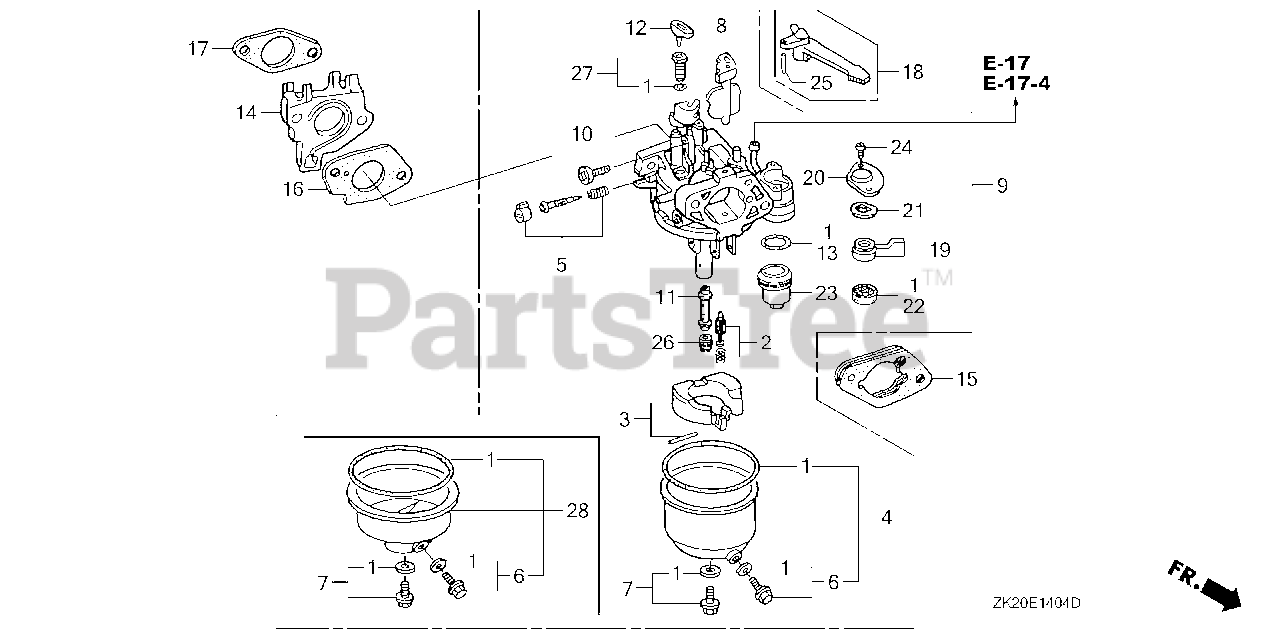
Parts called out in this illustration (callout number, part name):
1	GASKET SET (INCLUDES 16173-001-004)
2	VALVE SET, FLOAT
4	CHAMBER SET, FLOAT
5	SCREW SET, PILOT
6	SCREW SET, DRAIN
7	SCREW SET
9	CARBURETOR ASSY. (BE70B B/C)
10	SCREW, THROTTLE STOP
11	NOZZLE, MAIN
12	COLLAR, SETTING
13	GASKET, FUEL STRAINER CUP
14	INSULATOR, CARBURETOR
15	SPACER, CARBURETOR
16	GASKET, CARBURETOR
17	GASKET, INSULATOR
18	LEVER, CHOKE (STD)
19	LEVER, PETCOCK (CARBURETOR NO.)
20	PLATE, LEVER SETTING (CARBURETOR NO.)
21	SPRING, PETCOCK LEVER
22	GASKET, PETCOCK
23	CUP, FUEL STRAINER
24	SCREW, PAN (3X6)
24	SCREW, PAN (3X8) (CARBURETOR NO.)
25	PIN, SPRING (2X12)
26	JET, MAIN (#82) (CARBURETOR NO.)
26	JET, MAIN (#85) (CARBURETOR NO.)
26	JET, MAIN (#88) (CARBURETOR NO.)
27	JET SET, PILOT (#40) (CARBURETOR NO.)
28	CHAMBER SET, FLOAT (CARBURETOR NO.)
